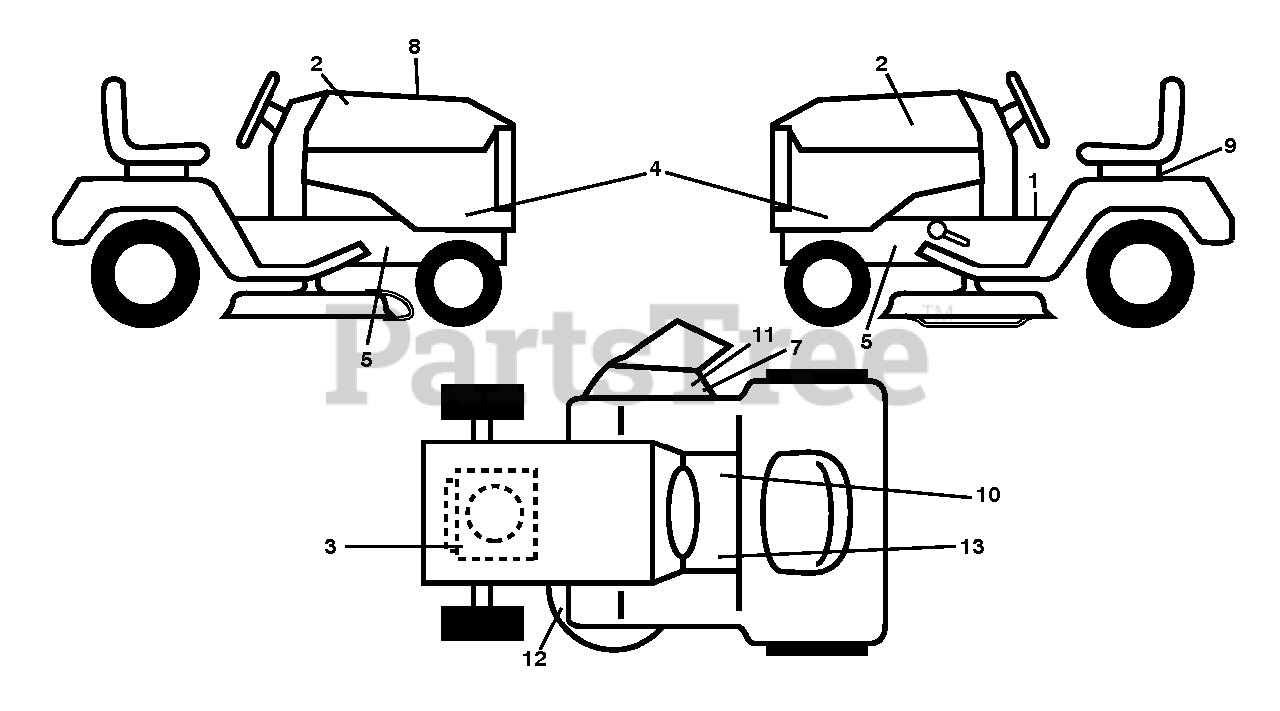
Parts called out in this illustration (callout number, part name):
1	DECAL.READ.OWN.MAN.SYMBOL.LT
2	DECAL.BADGE.170MM.TEXTLOGO.
3	DECAL.ENGINE.WARNING
4	DECAL DECAL.SDPNL.HUSQLT.LTH20
5	DECAL.CHASSIS.HOT.MUFFLER
7	DECAL.DFLCTR.WARNNG.CTFNGR.SYM
8	DECAL DECAL.RPL.BSM33.ENDU.TLW
9	DECAL BTRY SYMBOLS
10	DECAL.PARKING.BRAKE.SADDLE.LT
11	DECAL.CUTFINGER.CE.02
12	DECAL.DECK.SCH.36,38,94.NONCR
13	DECAL.FNDR.SDLE.BRAKE.CLUTCH.6
